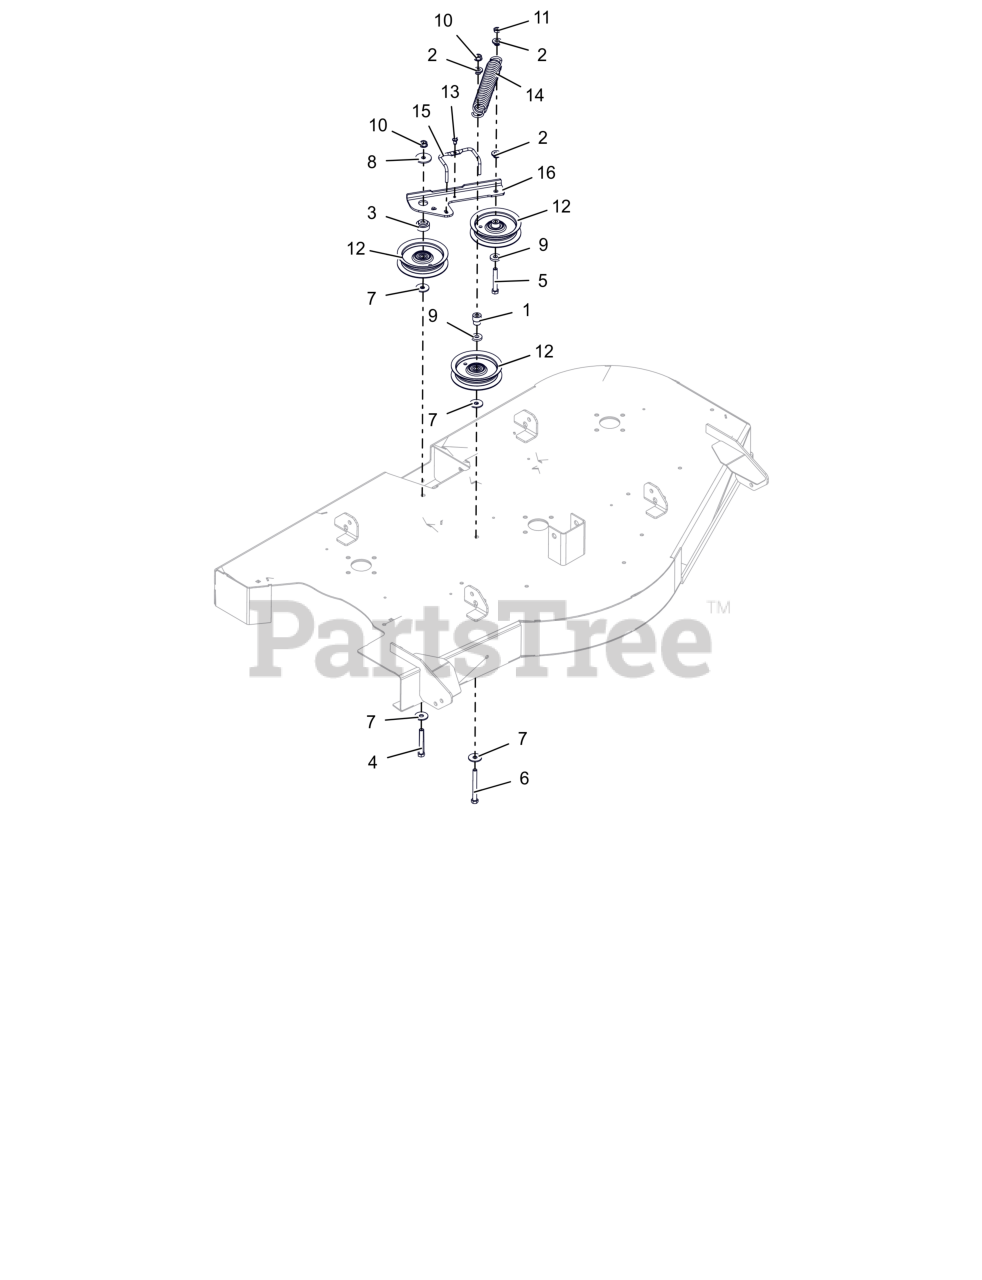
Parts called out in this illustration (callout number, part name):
1	BUSHING, IDLER (P/M)
2	BSHG-FLG .385X.500X.875X.406
3	BSHG, FLANGED
4	BLT, HEX .38-16X2.75 G5 ZCC
5	BLT, HEX .38-16X2.50 G5 ZCC
6	BLT, HEX .38-16X3.50 G5 ZCC
7	WSHR FL STL .406X1.25X.10ZC120
8	WSHR, FLT .380X1.50X.125 ZCC
9	WSHR, FLT .406X1.00X.188 ZCC
10	NUT-LK-CTR-FLG .375-16 GF ZCC
11	NUT-LK-CTR-JAM .375-16 GB ZCC
12	IDLER, FLAT - 4.06" X .75"
13	SCR-TAP .25-20X.50 HWH ZCC
14	SPRG, EXTENSION .170X1.385X6.7
15	WIREFORM, BELT FINGER
16	ARM, IDLER ZT (RED)
